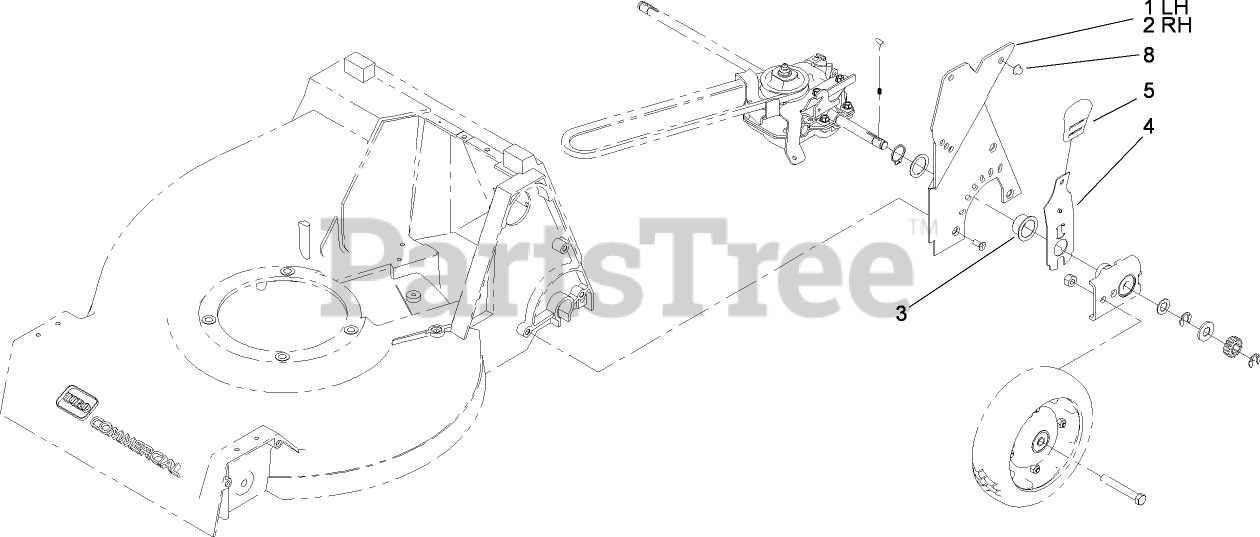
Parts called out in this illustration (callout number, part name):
1	PLATE-REAR HOC, LH
2	PLATE-REAR HOC, RH
3	BUSHING-FLANGE
4	REAR SPRING ARM ASM
5	KNOB-HOC
8	PUSHNUT-CAP, WASHER
